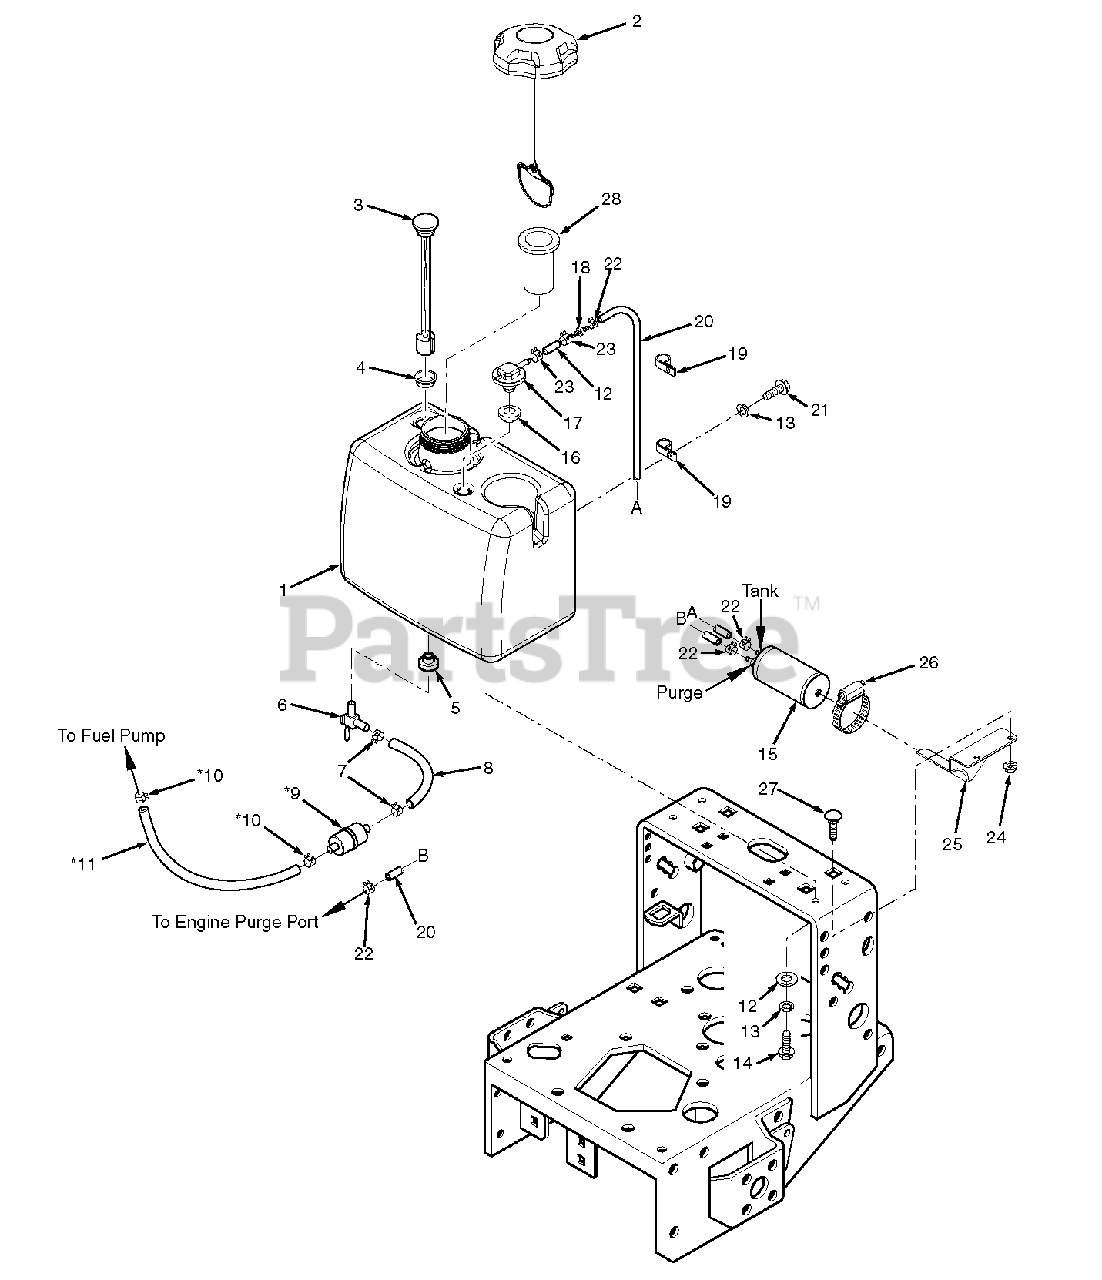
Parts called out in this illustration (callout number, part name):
1	Fuel Tank Assembly
2	Fuel Cap w/ Teether (C.A.R.B.)
3	Fuel Gauge Assembly
4	Seal, Fuel Gauge
5	Bushing, .56 Dia. Viton
6	Ball Valve w/Screen
7	Clamp, Fuel Hose
8	Fuel Hose, 1/4" ID
9	Fuel Filter
10	Clamp, Fuel Hose
11	Fuel Hose
12	Flatwasher, 5/16-.375 x .875 x .083
13	Lockwasher, 5/16" Spring
14	Bolt, Hex Head 5/16-18 x 1"
15	Carbon Canister
16	Grommet, Viton,
17	Fitting, Remote Vent
18	Mender, 1/4 x 3/16 w/.02 Hole
19	Clamp, 3/8"
20	Hose, Vapor Recovery 3/16"
21	Bolt, Hex Head 5/16-18 x 3/4"
22	Clamp, Vapor Recovery Hose 3/16"
23	Clamp, Fuel Hose 7/32" ID
24	Nut, Serrated Flange 5/16-18
25	Bracket, Canister Mounting
27	Bolt, Carriage 5/16-18 X 1"
28	Tube, Fuel Tank Insert - 4"
29	Hose, Vapor Recovery 1/4"
